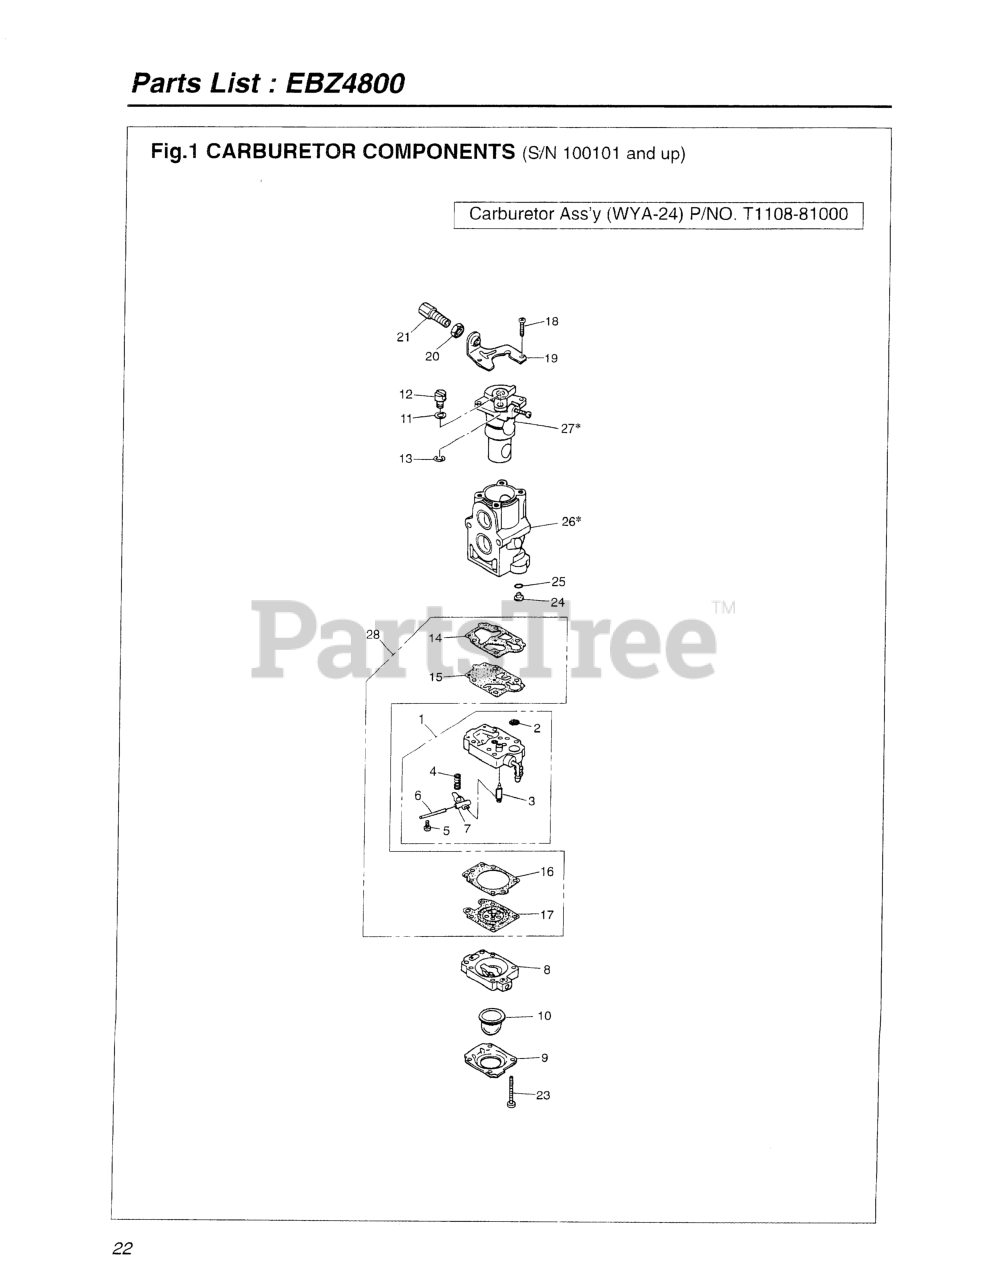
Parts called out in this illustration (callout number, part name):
1	BODY ASSY.
2	SCREEN
3	VALVE, INLET
5	SCREW
6	PIN
7	LEVER
8	BODY, PURGE
9	COVER, PUMP
10	PUMP, PRIMING
11	WASHER
12	SWIVEL
13	RING
14	GASKET
15	DIAPHRAGM
16	GASKET
17	DIAPHRAGM
18	SCREW
20	NUT, CABLE ADJUSTER
21	SCREW, CABLE ADJUSTER
23	SCREW
24	JET 43.5
25	RING, O
26	CARBURETOR (WYA 24A)
27	CARBURETOR (WYA 24A)
